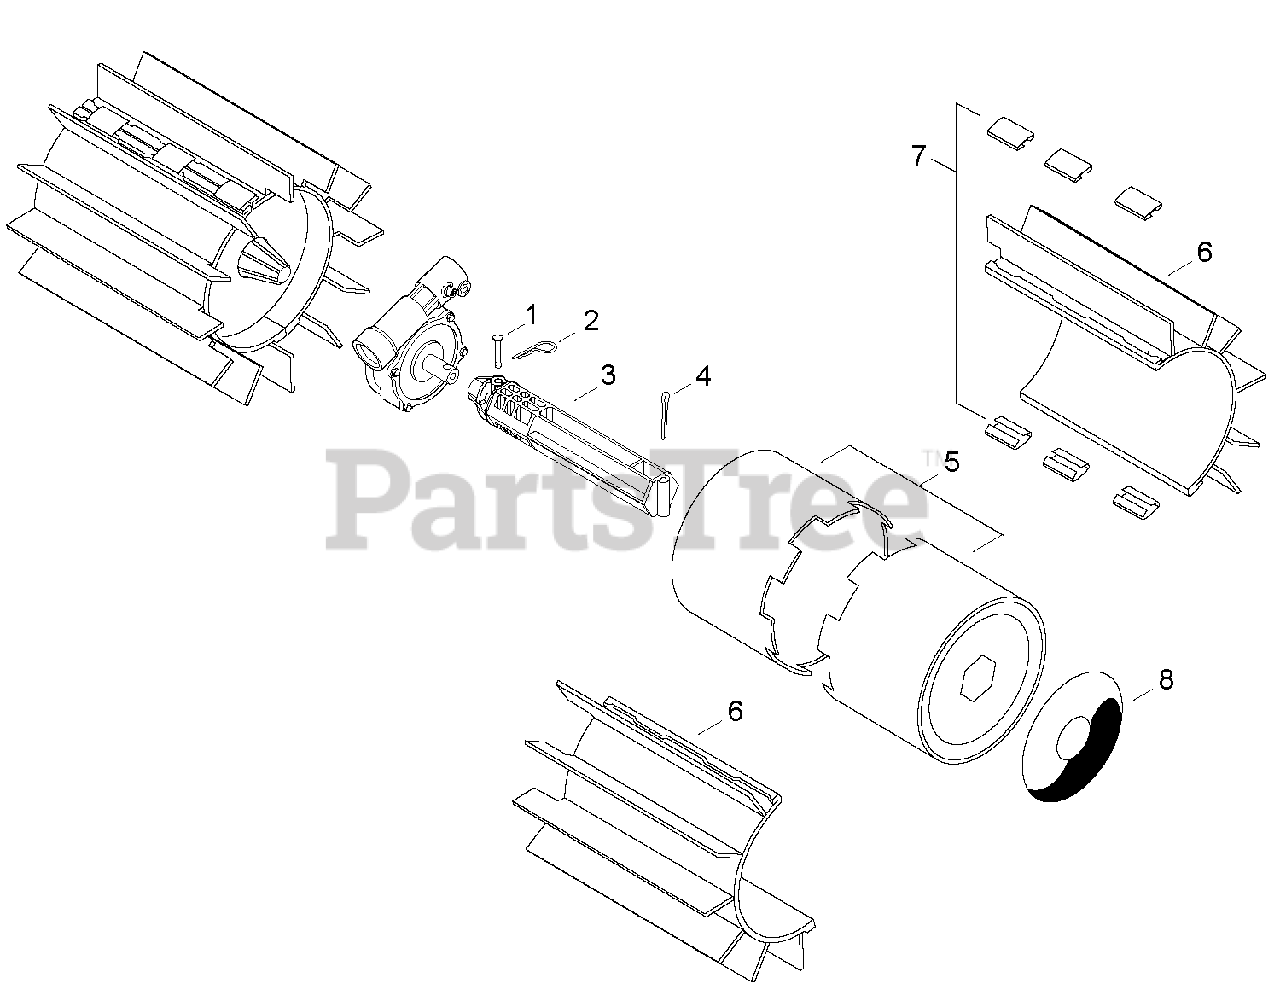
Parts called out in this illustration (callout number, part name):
1	PIN, CLEVIS
2	PIN, HITCH
3	AXLE, DRUM
4	PIN, COTTER
5	HUB, DRUM
6	BELT, SWEEPER
7	CLIP, BELT
8	LABEL, POWERBROOM
